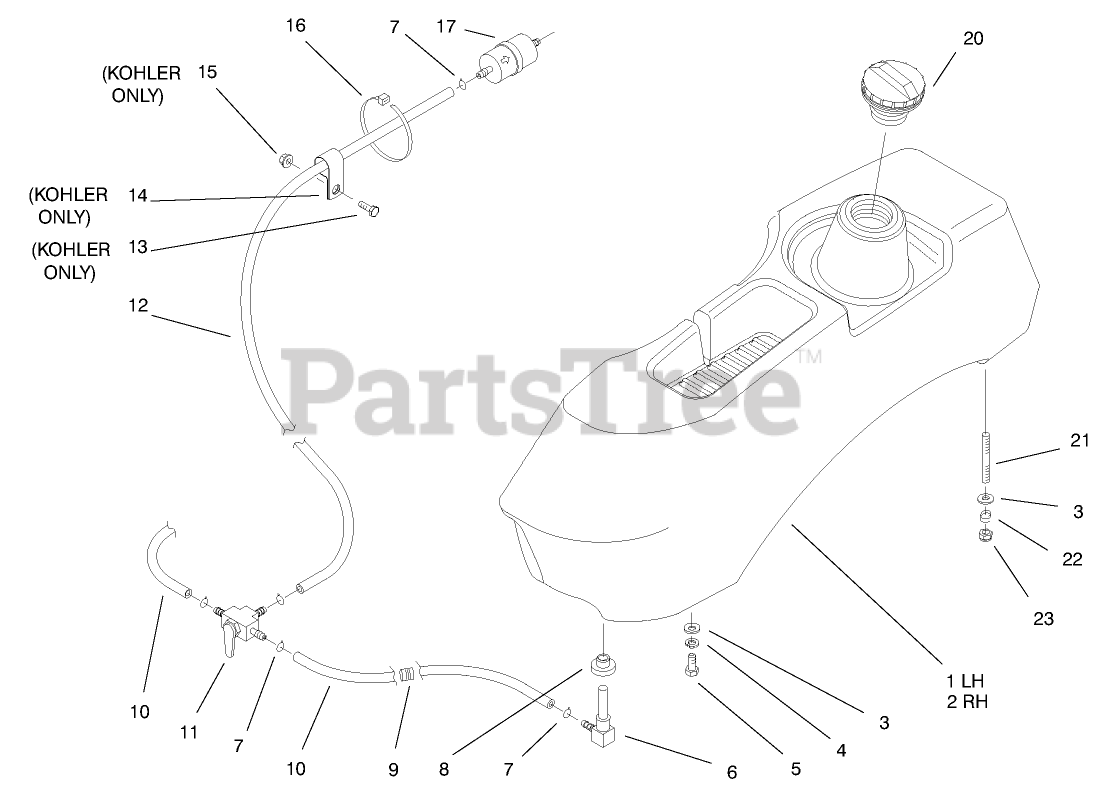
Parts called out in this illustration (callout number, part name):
1	TANK-FUEL, LH
2	TANK-FUEL, RH
3	WASHER-PLAIN
4	WASHER-LOCK
5	SCREW-HH
6	Elbow
7	Clamp
8	Bushing
9	Grommet-Fuel Line
10	Fuel Line
11	Valve-Fuel Line
12	Fuel Line
13	SCREW-HH
14	Clip
15	NUT-LOCK, NI
16	Tie-Plastic
17	Filter-Fuel
20	CAP-FUEL
21	Stud
22	Spring-Fuel Tank
23	Nut-Lock
